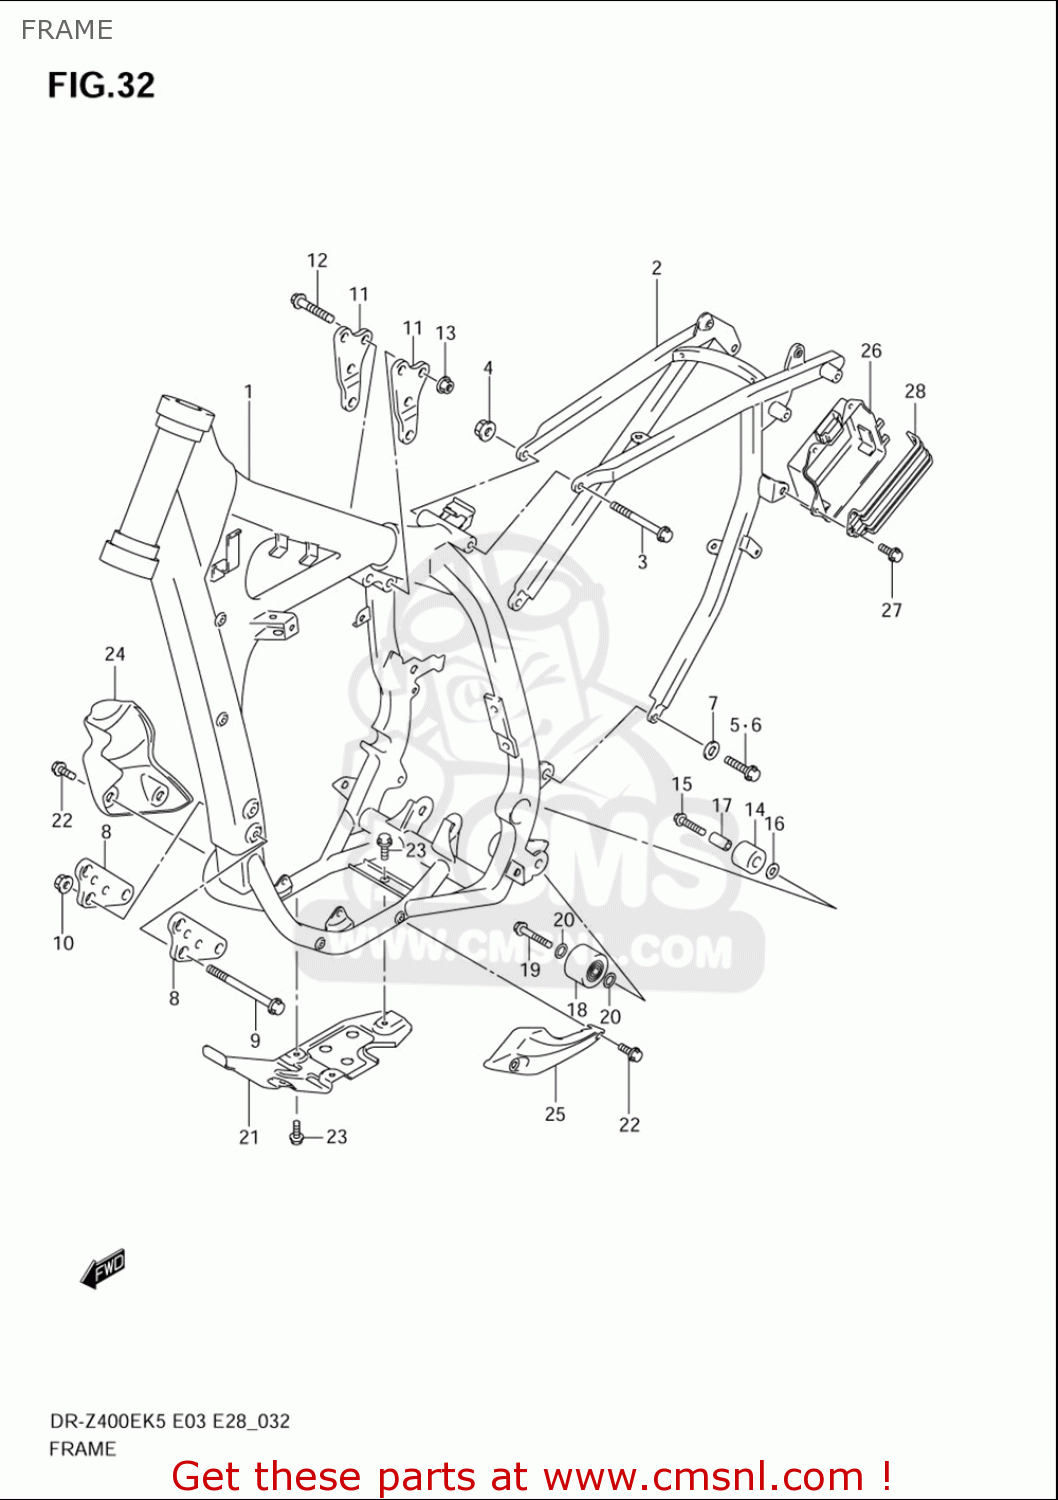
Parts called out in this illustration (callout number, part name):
1	FRAME (GRAY)
2	RAIL COMP,SEAT
3	BOLT(8X115)
4	NUT
5	BOLT(8X18)
6	BOLT(8X20)
7	WASHER(8.5X18X2)
8	PLATE,ENG MTG FR
9	BOLT(8X90)
10	NUT
11	PLATE,HEAD MTG RR
12	BOLT(8X50)
13	NUT
14	ROLLER,CHAIN CONTROL UPR
15	BOLT(8X41)
16	WASHER
17	SPACER(8.6X12.2X26.5)
18	ROLLER,CHAIN
19	BOLT(8X41)
20	SHIM(8X12X1)
21	PROTECTOR,ENGINE
22	BOLT(8X16.5)
23	BOLT
24	WATER PUMP GUARD SET
25	MAG COVER GUARD SET
26	HOLDER,BATTERY
27	BOLT(6X17.8)
28	BAND,BATTERY HOLDER
